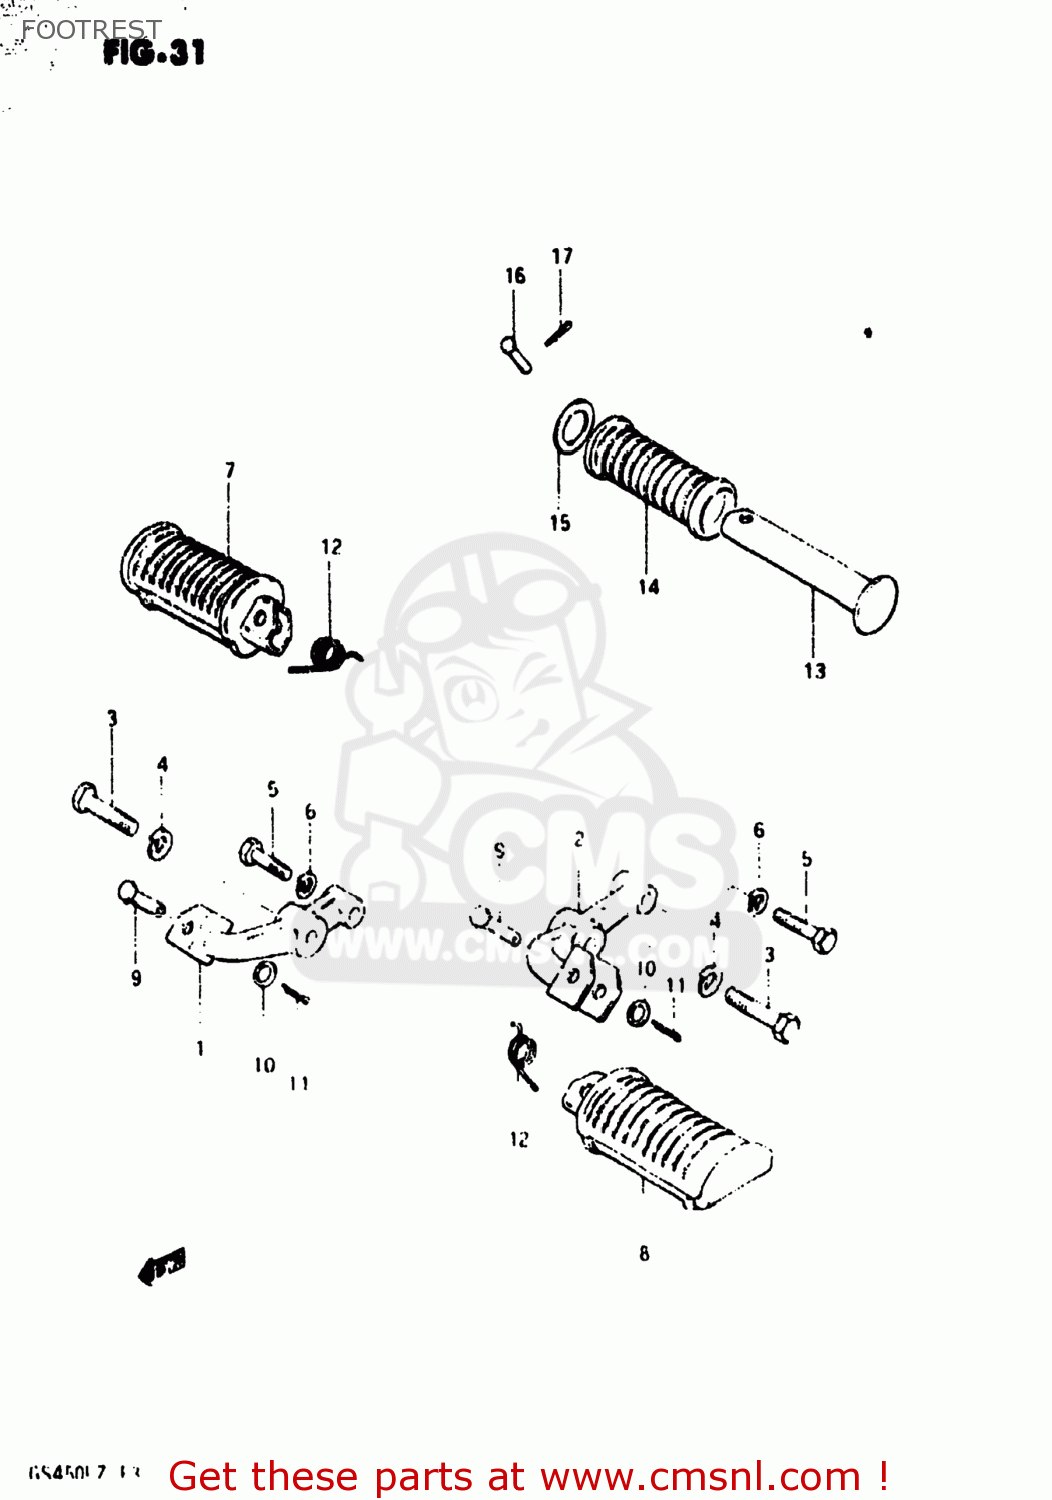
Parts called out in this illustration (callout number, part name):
1	BAR,FRONT FOOTREST,RIGHT
2	BAR,FRONT FOOTREST,LEFT
3	BOLT
4	LOCK WASHER
5	BOLT 8X40
6	LOCK WASHER
7	RUBBER,FRONT FOOTREST
8	FOOTREST
9	PIN
10	WASHER
11	PIN
12	SPRING
13	BAR,PILLION FOOTREST
14	RUBBER,PILLION FOOTREST
15	WASHER (19.5X32X2)
16	PIN
17	PIN
